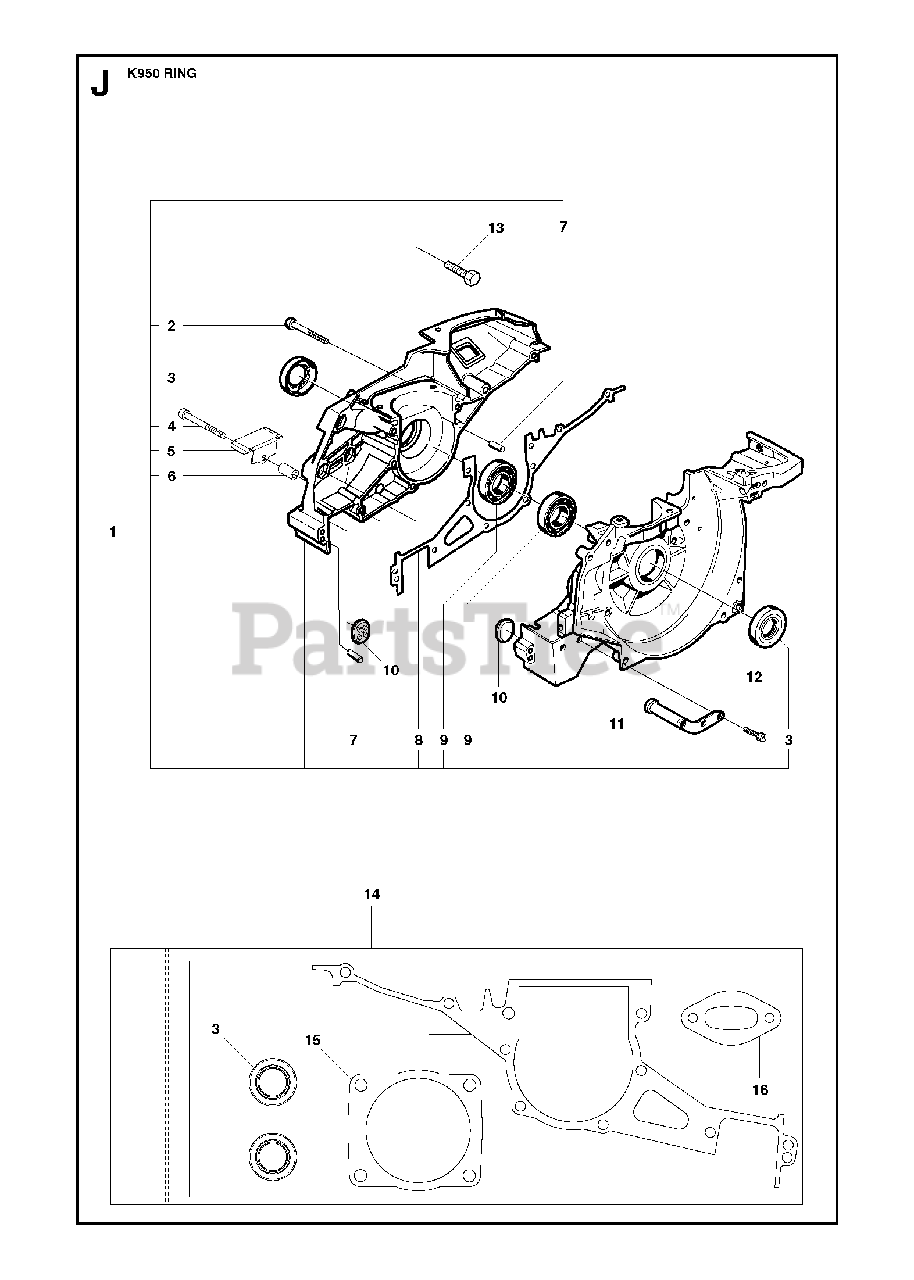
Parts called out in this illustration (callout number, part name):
1	CRANKCASE ASSYIncl. 2 - 9
3	SEALING RINGGasket kit 14
7	PARALLEL PIN
9	BALL BEARING
12	SCREW IHSCFM
15	CYLINDER BASE GASKET
16	GASKET
